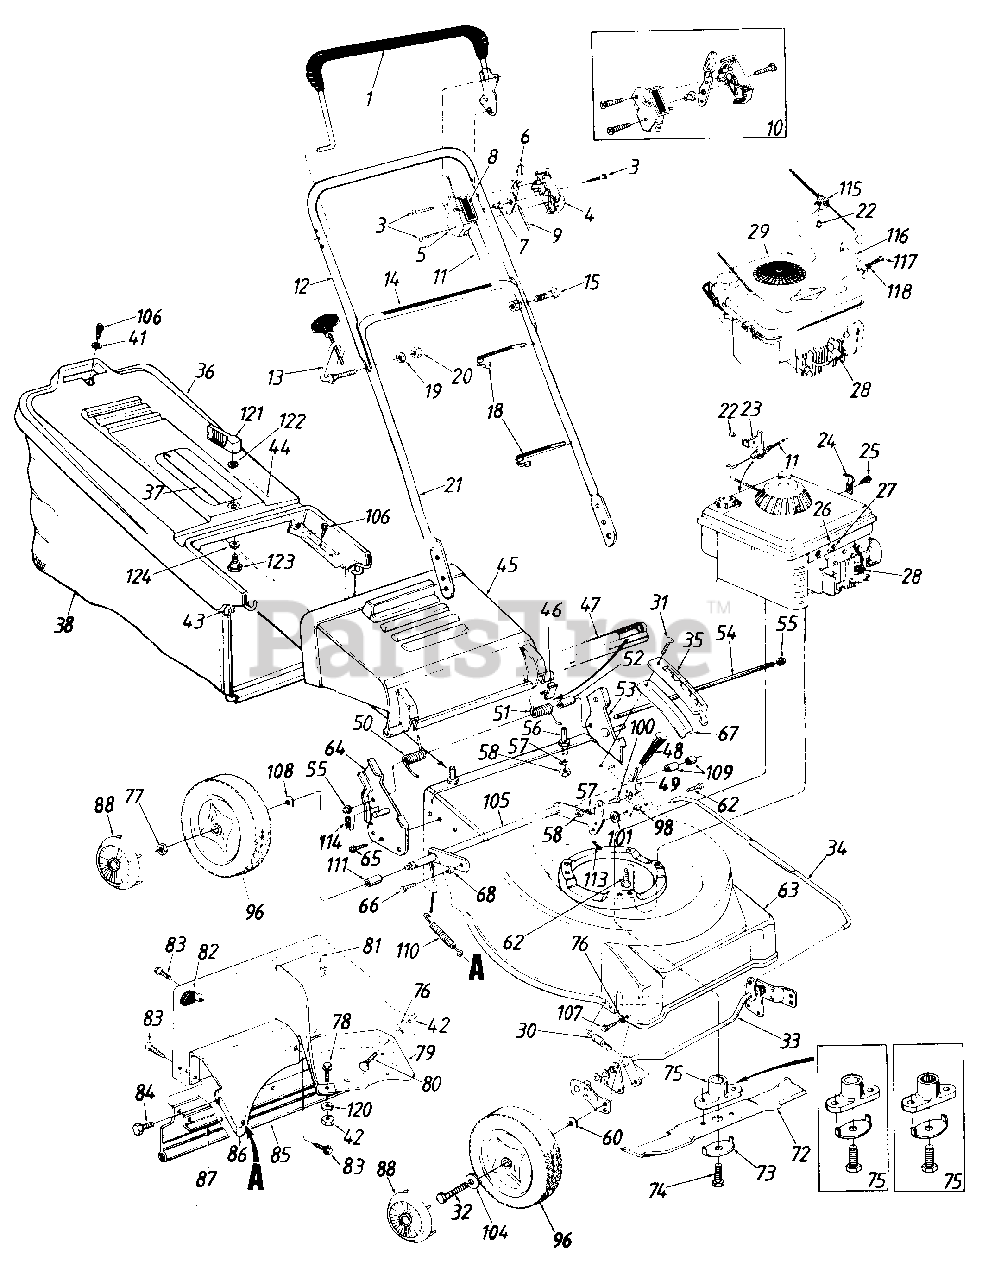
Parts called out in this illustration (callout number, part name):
1	Control Handle Ass'y.
3	Truss Mach. B-Tap Scr. #12 x 1.5" Lg.
4	Control Panel Half
5	Clutch Panel Half
6	Throttle Control Lever
7	Control Disc Pin
8	Control Label-Throttle
9	Throttle Wire-58" Lg.
10	Control Housing Comp.
11	Control Cable-43" Lg.
12	Upper Handle (Painted)
13	Rope Guide Bolt
14	Instruction Label-Handle
15	Curved Carriage Bolt 5/16-18 x 1.38" Lg.
18	Cable Tie
19	L-Wash. 5/16" I.D.
20	Hex Nut 5/16-18 Thd.*
21	Lower Handle (Painted)
22	Pop Rivet .156" Dia. x .379"
23	Cable Bracket
24	Casing Clamp
25	Hex B-Tap Scr. #10 x .38" Lg.
26	Casing Clamp
27	Hex B-Tap Scr. #10 x .62" Lg.
28	Spark Plug Boot
29	Engine
30	Extension Spring 2.39" Lg.
31	Torx Hd. AB-Tap Scr. 1/4"-.62" Lg.
32	Axle Bolt
34	Height Adj. Connecting Rod
35	Height Adjustment Plate
36	Hardtop Bag Cover
37	Hardtop Handle
38	Grass Bag
41	Fl-Wash. .281" I.D. x .62" O.D.
42	Hex Nut 1/4-20 Thd.
43	Front Catcher Frame
44	Rear Catcher Frame
45	Chute Deflector
46	Deflector Plug
47	Seal-Extrusion
49	Spring Lever
50	Torsion Spring-R.H.
51	Torsion Spring-L.H.
52	Spacer.255" I.D.
53	Handle Brkt. Ass'y.-L.H.
54	Hinge Pin 17.75" Lg.
55	Cap Speed Nut
56	Shld. Pin 3/8-24 x 1.43" Lg.
57	L-Wash. 3/8" I.D.
58	Hex Jam Nut 3/8-24 Thd.
60	Bell-Wash. .38" I.D. x .88" O.D.
62	Hex L-Wash. Hd. Scr. 3/8-16x 1" Lg.
63	21" Deck Ass'y.
64	Handle Brkt. Ass'y.-R.H.
65	Hex L-Wash. Hd. AB-Tap Scr. 1/4 x.62" Lg.
66	Hex Wash. Hd. Tap Scr. 3/8-16 x .75" Lg.
67	Height Adjustment Support
68	Spacer.385" I.D.
72	21" Blade
73	Blade Bell-Wash. .44" I.D. x 2.38"
74	Hex Bolt 3/8-24 x 1.5" Lg.
75	Blade Adapter Kit (Keyed)
76	L-Wash. 1/4" I.D.
77	Hex Jam Nut 1/2-20 Thd.
78	Hex Bolt 1/4-20 x .85" Lg.
79	Rear Belt Baffle
80	Carr. Bolt 1/4-20 x .50" Lg.*
83	Torx Mach. AB-Tap Scr. 1/4 x .62" Lg.
84	Hex B-Tap Scr. 1/4 x .38" Lg.
85	Rear Flap
96	Wheel Ass'y. Comp.
98	Shld. Spacer .50" Dia.
100	Shld. Pin 3/8-24 x 1.43" Lg.
101	Fl-Wash. .375" I.D. x 1.0"
104	Fl-Wash. .531" I.D. x .93"
105	Rear Axle Ass'y.
106	Hex L-Wash. AB-Tap Scr. 1/4 x, .62" Lg.
107	Hex L-Wash. HD AB-Tap Scr. 1/4 x .38" Lg.
108	Fl-Wash. .510" I.D. x .75"
109	Spacer. 526" I.D.
110	Extension Spring 3.8" Lg.
111	Sleeve.526" I.D.
113	Cotter Pin 3132" Dia. x .75"
114	Internal Cotter Pin 5/16" Dia.
115	Cable Mtg. Brkt.
116	Mounting Brkt.
117	Truss Mach. Scr. #10 x .5" Lg.
118	L-Wash. #10 I.D.
120	Bell-Wash. 1/4" I.D.
121	Grass Catcher Locking Knob
122	Internal L-Wash. 1/4" I.D.
123	Shld. Bolt .342" Dia. x .268
124	Wave Washer 3/8" I.D.
